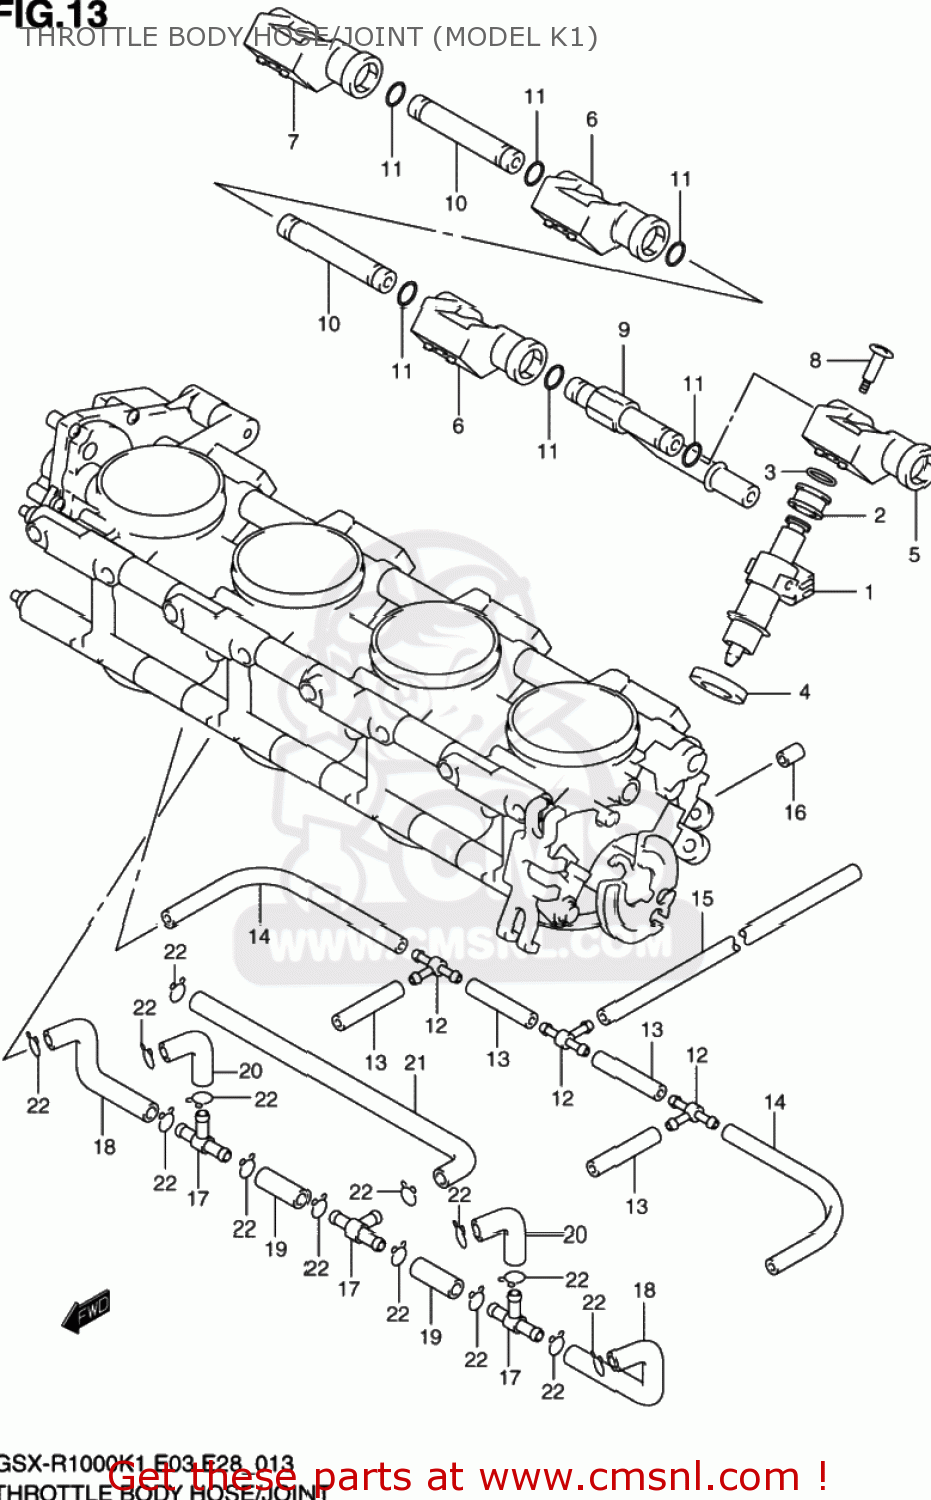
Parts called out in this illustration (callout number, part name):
1	INJECTOR ASSY
2	RING,CUSHION
3	O RING
4	RING,SEAL
5	JOINT,NO.1
6	JOINT,NO.2,3
7	JOINT,NO.4
8	SCREW
9	JOINT
10	JOINT
11	O RING
12	JOINT
13	HOSE,RUBBER(L:35)
14	HOSE,RUBBER(L:100)
15	HOSE,RUBBER(3X7X170)
16	CAP,RUBBER
17	JOINT
18	HOSE,RUBBER(L:80+25)
19	HOSE,RUBBER(L:35)
20	HOSE,RUBBER(L:30+30)
21	HOSE,RUBBER(L:200+30)
22	CLIP
